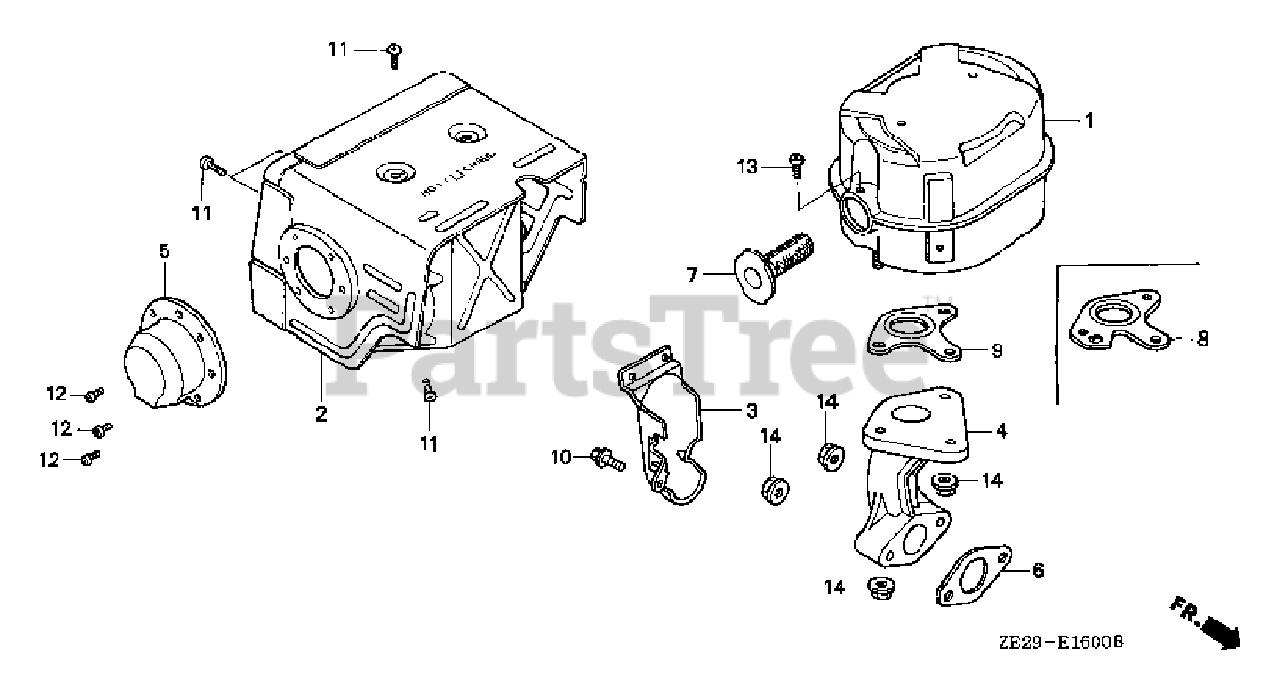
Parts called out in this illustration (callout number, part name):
1	MUFFLER
2	PROTECTOR, MUFFLER
3	PROTECTOR, EX. PIPE
4	PIPE, EX.
5	CAP, MUFFLER
6	GASKET, EX. PIPE
6	GASKET, EX. PIPE (WACKER)
7	ARRESTER, SPARK
8	GASKET, MUFFLER (ARRESTER)
9	GASKET, MUFFLER
10	BOLT, FLANGE (6X12) (CT200)
11	SCREW, TAPPING (5X8)
12	SCREW, TAPPING (4X6)
13	SCREW, TAPPING (5X8)
14	NUT, FLANGE (8MM)
